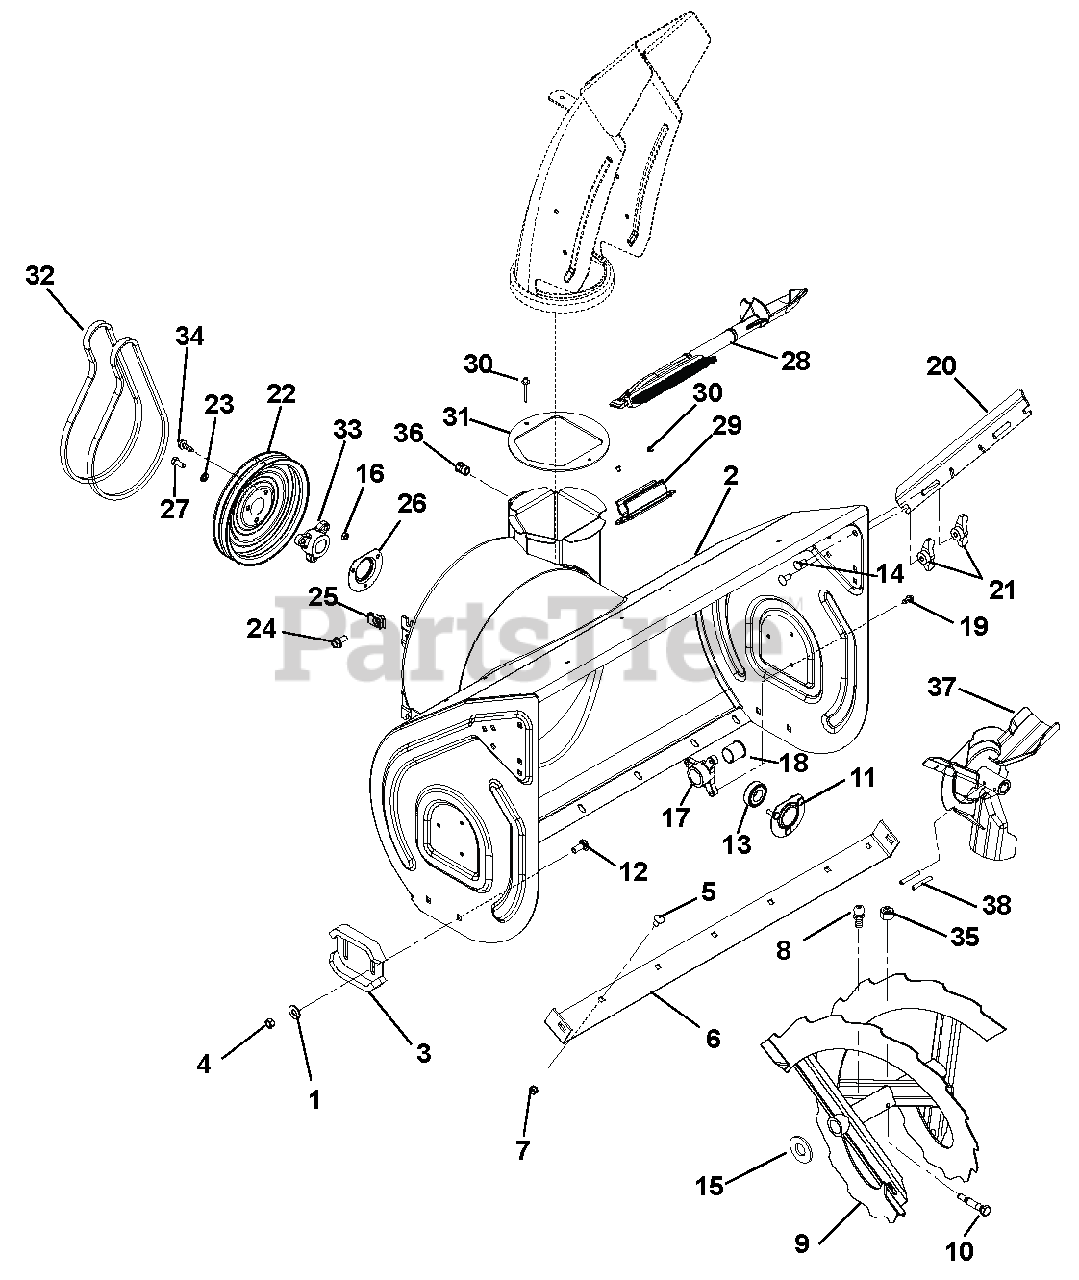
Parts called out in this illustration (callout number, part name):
1	@WSHR-FL-STL.438X1.00X.083 YWZ
2	BLOWER HOUSING W/DECAL 28"
2	BLOWER HOUSING W/DECAL 32"
2	BLOWER HOUSING W/DECAL 36"
3	RUNNER, SKID SHOE
4	@NUT-LK-CTR .38-16 YWZC
5	BOLT, MODIFIED HEAD CARRIAGE
6	BLADE, SCRAPER-28"
6	BLADE, SCRAPER-32"
6	BLADE, SCRAPER-36"
7	@NUT-LK-TOP-FLG .31-18 YWZC
8	ZERK,FITTING .25X.125 DRIVE IN
9	RAKE, LH-28"(1 ID X 15.75 OD)
9	RAKE, RH-28"(1 ID X 15.75 OD)
9	RAKE, LH-32"(1 ID X 15.75 OD)
9	RAKE, RH-32"(1 ID X 15.75 OD)
9	RAKE, LH-36" (1 ID X 15.75 OD)
9	RAKE, RH-36"(1 ID X 15.75 OD)
10	SHEAR BOLT SERVICE ASSEMBLY
11	BEARING FLANGE
12	@BLT-RDHDSHSQNK.38-16X1.0 G5YZ
13	BRG-BALL .876X1.75X.50 RSTFP
14	@BLT-RHDSSQNK .31-18X.75 G5YZ
15	WSHR-FL-STL 1.010X1.505X.062YZ
16	@NUT-LK-CTR .25-20 YWZC
17	BUSHING, RAKE SHAFT 1"
18	BSHG-FLG SPLIT NYLINER 1.0" HP
19	SCR-TAP .25-20X.50 HWH TR YWZ
20	CUTTER, DRIFT
21	KNOB,WING .31-18 UNC NYL/TALC
22	PULLEY, SPIN FORM DUAL GROOVE
23	WSHR-LK .312X.097 HVY YWZC
24	BLT-SERHFWH .38-16X.75 YWZC
25	NUT-RTNR .375-16X.37
26	BEARING FLANGE
27	BLT-HEX .31-24X.75 YWZC GR5
28	DEVICE, SNOW CLEAN OUT W/BRUSH
29	MOUNT, SNOW CLEAN OUT
30	RVT-POP .187 YZ
31	BAFFLE, DISCHARGE NECK
32	V-BELT, HA-RAW EDGE (SET)
33	PULLEY HUB, D-BORE .87 PRO
34	@SCR-TAP .31-18X.50 HWH TR YWZ
35	@NUT-LK-CTR .31-18 YWZC
36	NUT, THREADED INSERT .38-16
37	IMPELLER, 3 BLADE-14"
38	PIN-ROLL .250X1.75
